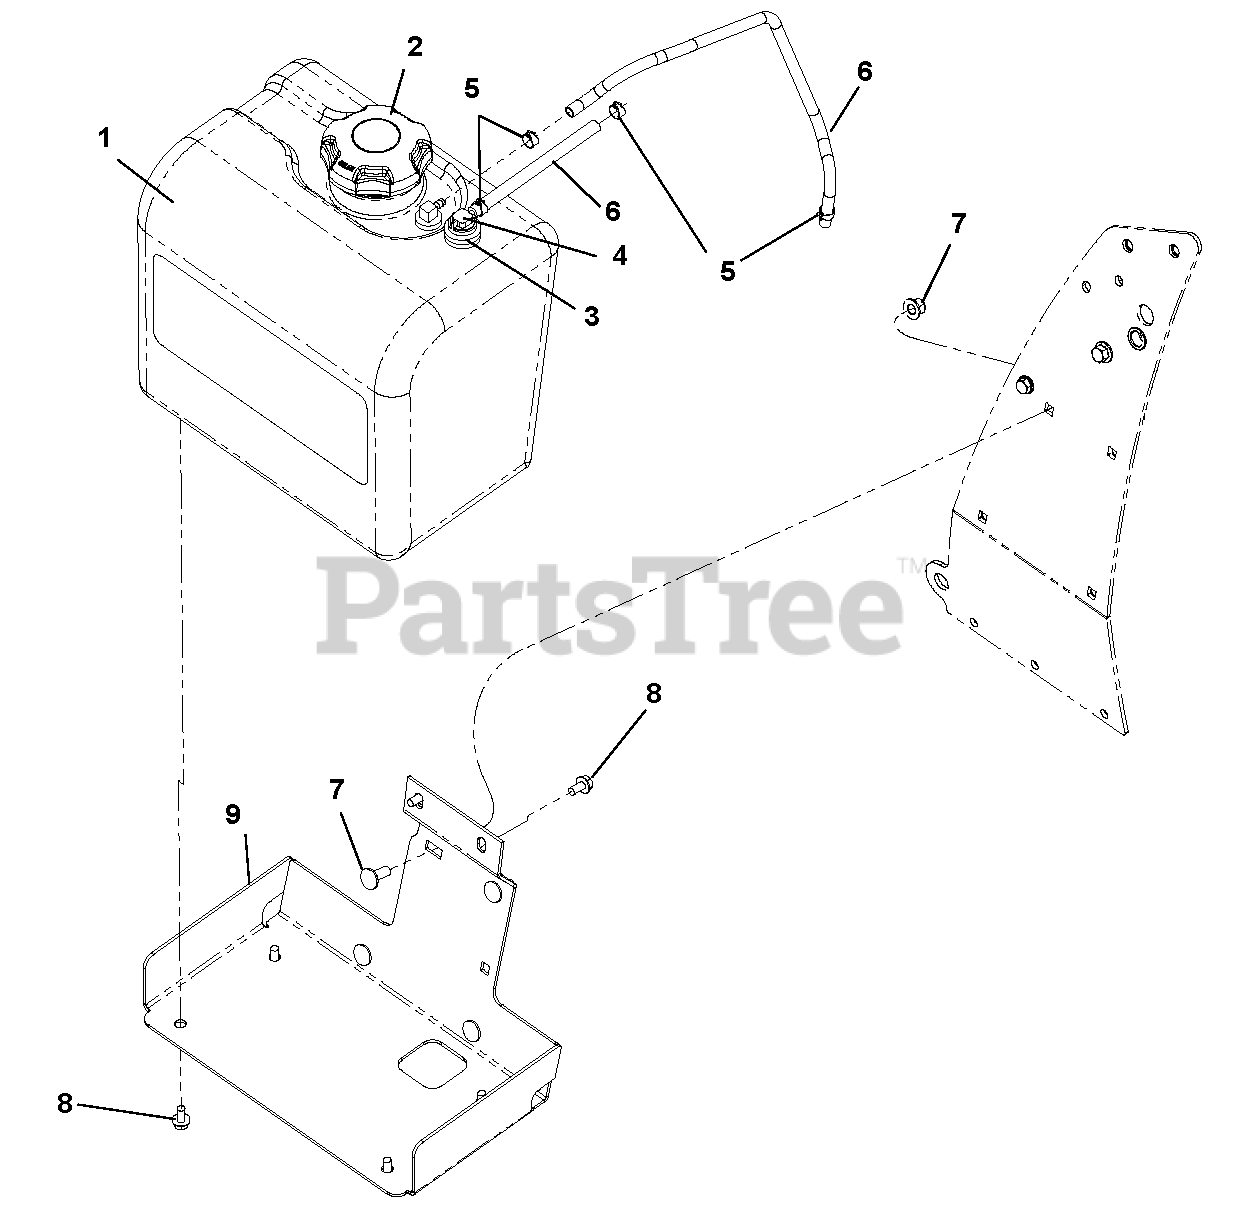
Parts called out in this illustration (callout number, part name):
1	Assy, Gravely EPA Fuel Tank (Inclludes items 2, 3, 4)
2	Cap, Fuel
4	Fuel Pickup
5	Clamp, Fuel Line
6	Hose, .25 Low-Perm Bulk Gas (33.5 and 22")
7	Nut, Spin Lock Flange .375-16 YWZC
8	Bolt, Round Head Square Neck .375-16 x 1.00 Grade 5
9	Screw, Hex Flat M8 x 1.25 x 16 10.9
10	Bracket, Fuel Tank Mounting
